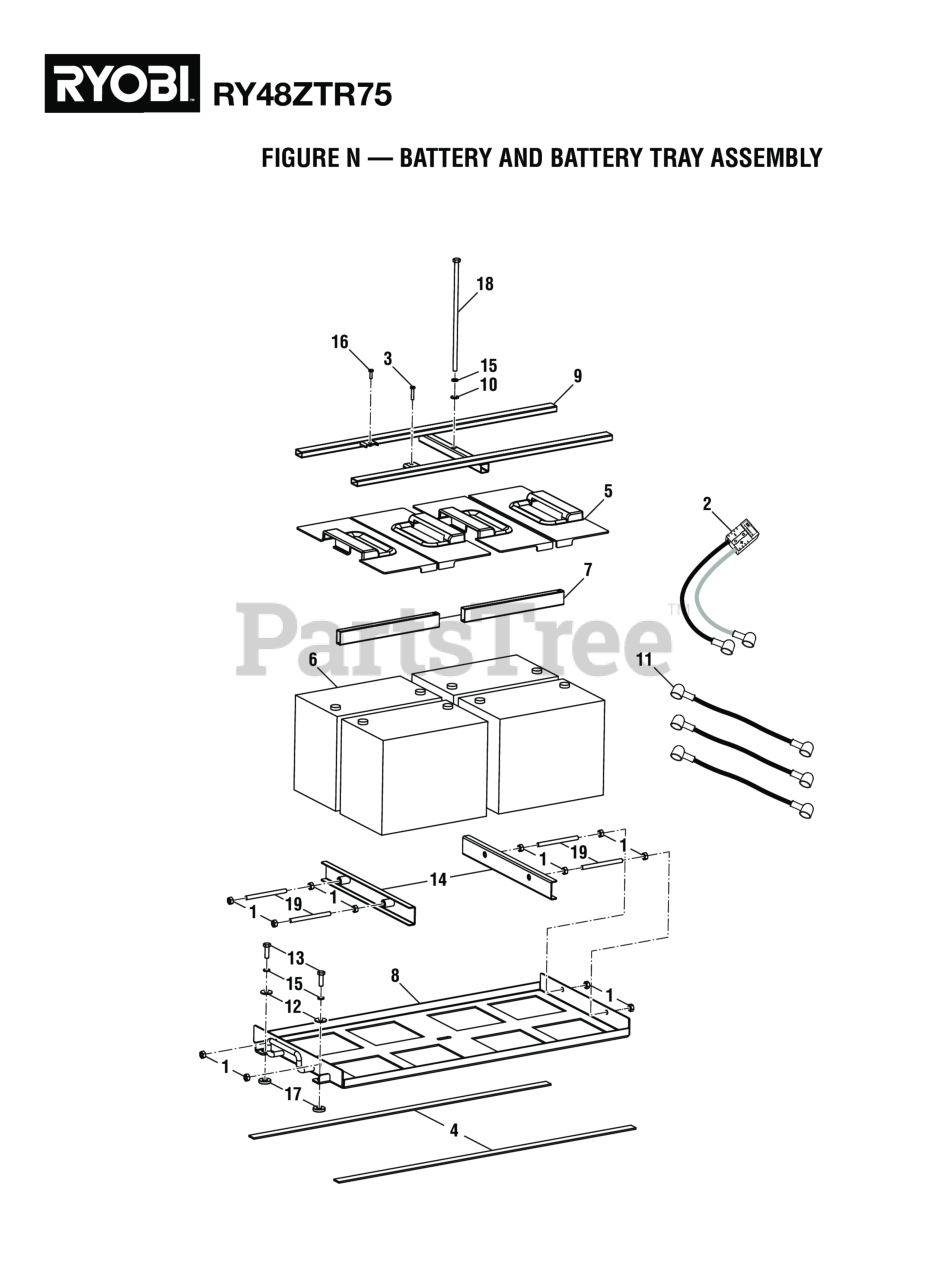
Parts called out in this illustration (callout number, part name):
1	Hex Nut (M8)
2	Battery Cable 2, ZTR
3	Screw (M5 x 25 mm)
4	Battery Tray Slider
5	Battery Shield, ZTR
6	Battery (LPC12-75, RY48110, RY48112)
7	Battery Spacer (LPC12-75)
8	Battery Tray
9	Battery Tie Down
10	Washer (OD16 x ID8.4 x 1.6t)
11	Battery Cable w/Covers (Red and Black, 120 mm)
12	Washer (OD 24 x ID8.4 x 2t)
13	Bolt (M8 x 25 mm, Hex Hd.)
14	Battery Holder Bracket
15	Lock Washer (OD9.8 x ID8.5 x 5t)
16	SCREW,PPHMS, M5 X 0.8 X 16 - STEEL,
17	Metal Bushing
18	Hex Bolt (M8 x 240 mm)
19	Threaded Rod (M8 x 100 mm)
